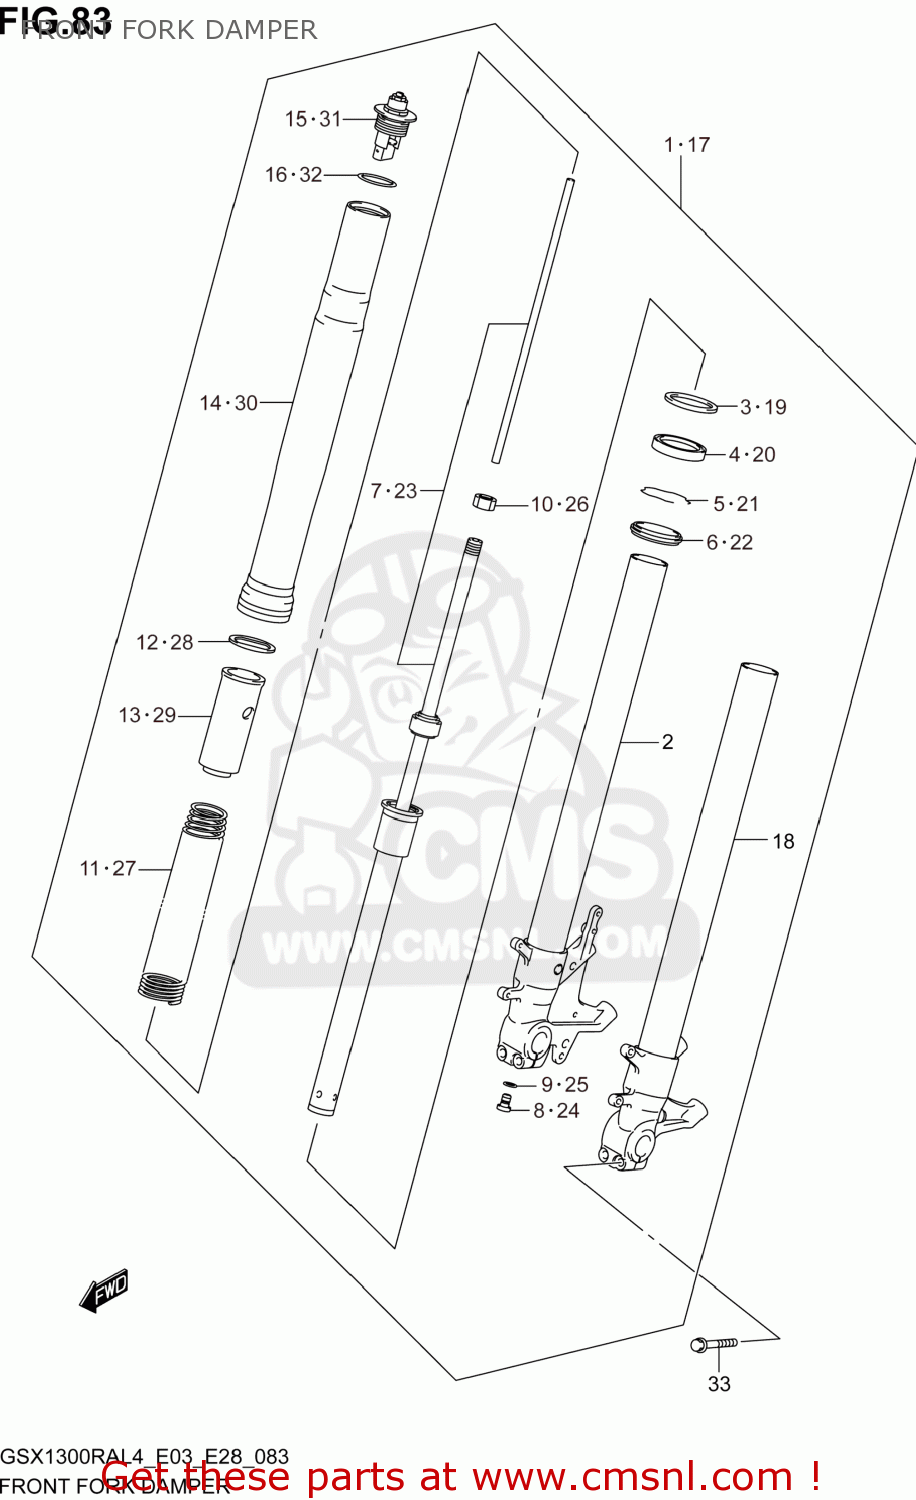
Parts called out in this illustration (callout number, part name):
1	DAMPER ASSY,FRONT FORK,R
2	TUBE,INNER,R
3	WASHER
4	SEAL,OIL
5	RING,STOPPER
6	SEAL,DUST
7	CYLINDER
8	BOLT
9	GASKET (NAS)
10	NUT,ROD
11	SPRING,FR
12	GUIDE,SPRING
13	SPACER,SPRING
14	TUBE,OUTER
15	CAP,FR FORK
16	O RING
17	DAMPER ASSY,FR FORK,L
18	TUBE,INNER,L
19	WASHER
20	SEAL,OIL
21	RING,STOPPER
22	SEAL,DUST
23	CYLINDER
24	BOLT
25	GASKET (NAS)
26	NUT,ROD
27	SPRING,FR
28	GUIDE,SPRING
29	SPACER,SPRING
30	TUBE,OUTER
31	CAP,FR FORK
32	O RING
33	BOLT
